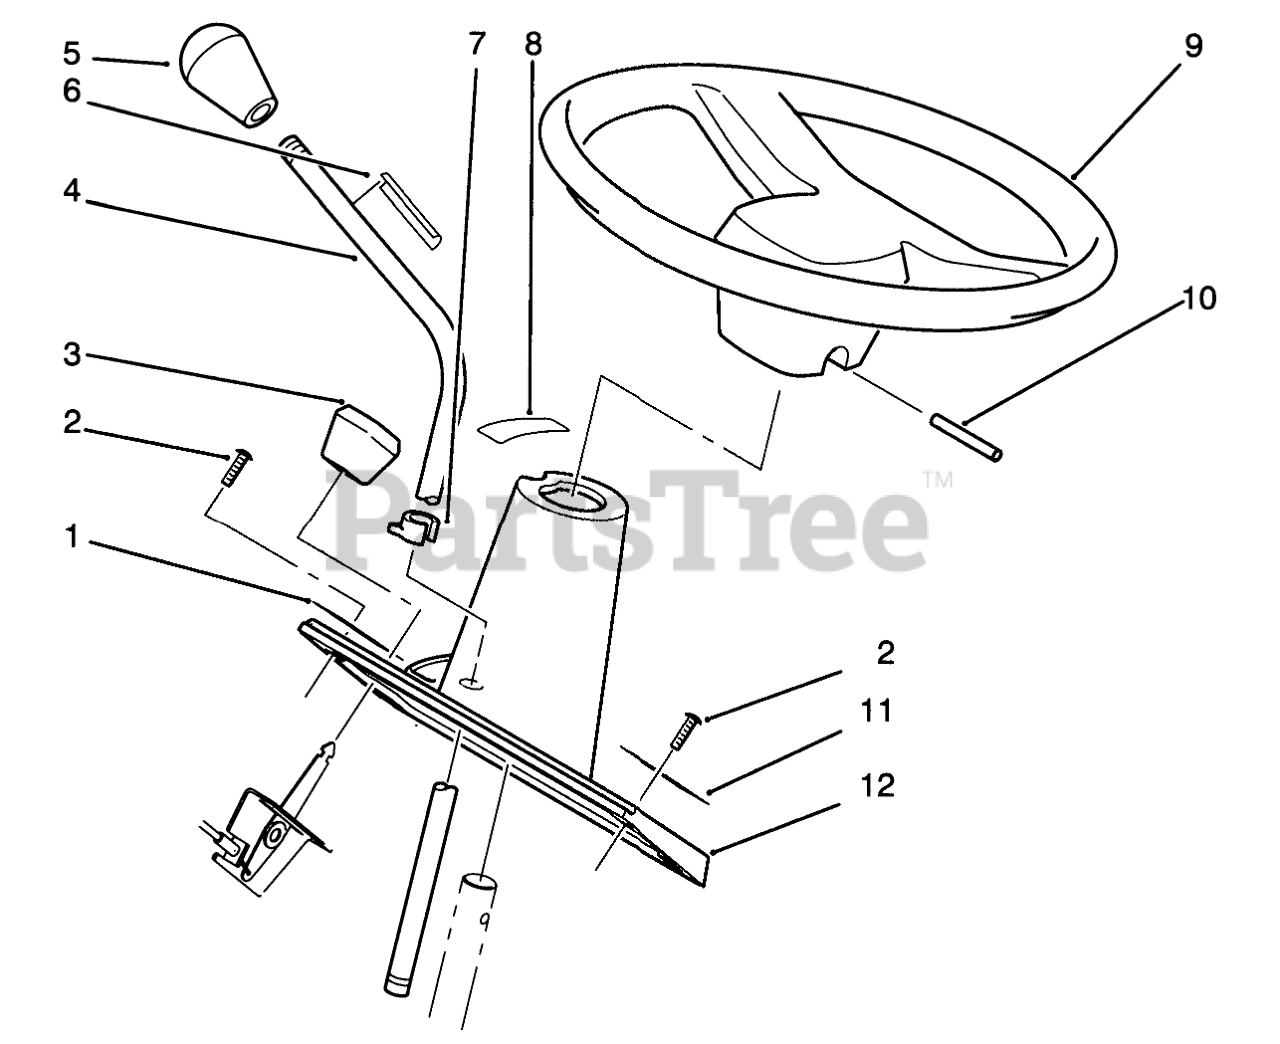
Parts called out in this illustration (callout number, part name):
1	DECAL-THROTTLE
2	SCREW
3	KNOB-THROTTLE
4	ROD-SHIFT LEVER
6	DECAL-MOTION CONTROL
7	POINTER
8	DECAL-HYDRO MOTION
9	STR'G-WHL 13" TORO
10	PIN-ROLL
11	DECAL-HEIGHT OF CUT
12	CONSOLE
